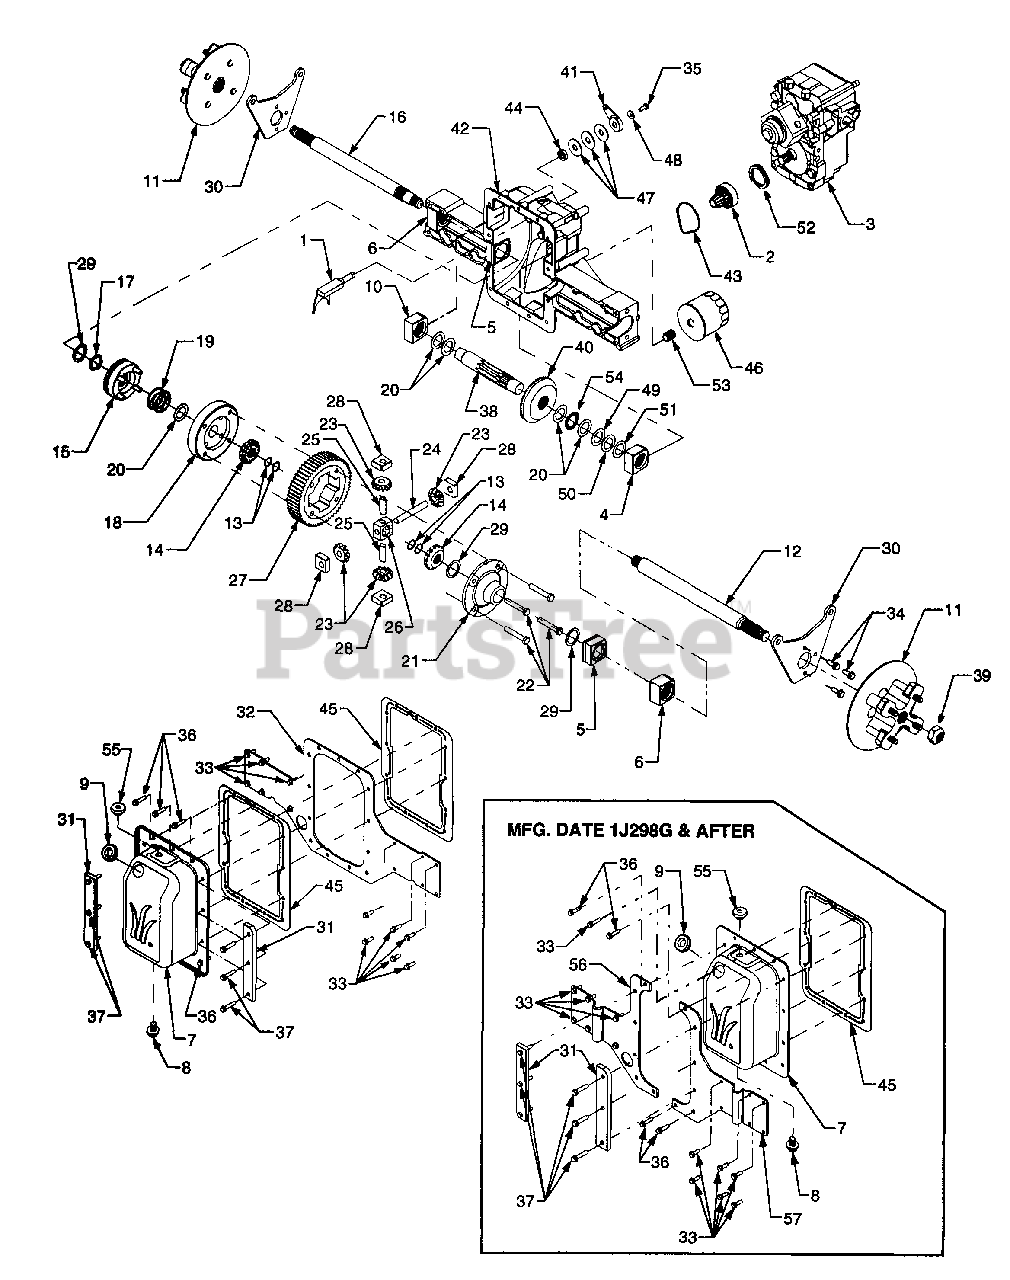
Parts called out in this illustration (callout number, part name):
1	Shaft, Differential Actuator
2	Gear Assembly, Pinion 13T
3	Hydrostatic Transmission Assy. Kit
4	Bearing Block Assembly, Needle
5	Bearing Block Assembly
6	Bearing Block Assembly
7	Cover Assembly, Rear
8	Plug, Drain, M14 x 1.5 x .827
9	Grommet, Rubber
10	Bearing Block Assembly
11	Hub Assembly, Wheel
12	Axle Shaft, 15.08 Long - RH
13	Retaining Ring
14	Gear, Spur, 14T
15	Collar Assembly, Diff. Lock
16	Axle Shaft, 15.08 Long - LH
17	Retaining Ring
18	Housing, Diff. Lock
19	Spring, Compression
20	Washer, Thrust, 1.007 x 1.542 x .03
21	Housing, Diff. Cover
22	Hex Cap Screw, 3/8-24 x 2.25 GR8
23	Gear, Differential 10T
24	Shaft, Cross, .5 x 3.485
25	Shaft, Cross, Special
26	Differential Pinion Block
27	Gear, Spur 60T
28	Block, Thrust Miter
29	Washer, Flat, 1.187 x 1.56 x .062
30	Bracket, Brake Mounting
31	Block, Transmission Cover
32	Plate, Transmission
33	Screw, Hex Wash. Hd. Tapp 1/4-20 x .75
34	Screw, Hex Wash. Hd. Tapp 5/16-18 x .875
35	Hex Cap Screw, 1/4-20 x .62 GR5
36	Screw, Hex Wash. Hd. Tapp 1/4-20 x 1.0
37	Screw, Hex Wash. Hd. Tapp 1/4-20 x 1.25
38	Shaft, Output 9T
39	Nut, Lock, 7/8-14
40	Gear, Bevel 54T
41	Arm, Diff. Lock Actuator
42	Housing, Differential w/Diff. Lock
43	O-Ring, 2.75 x .103
44	Seal, Oil
45	Gasket
46	Filter, Oil
47	Washer, Flat, .51 x 1.5 x .07
48	Washer, Belleville, .265 x .75 x .062
49	Washer, Flat Shim, 1.0 x 1.56 x .010
50	Washer, Flat Shim, 1.0 x 1.56 x .020
51	Washer, Flat Shim, 1.0 x 1.56 x .015
52	Washer, Spring
53	Fitting, Filter Nipple
54	Bearing, Needle Thrust
56	Plate, Trans. Support LH
57	Plate, Trans. Support RH
